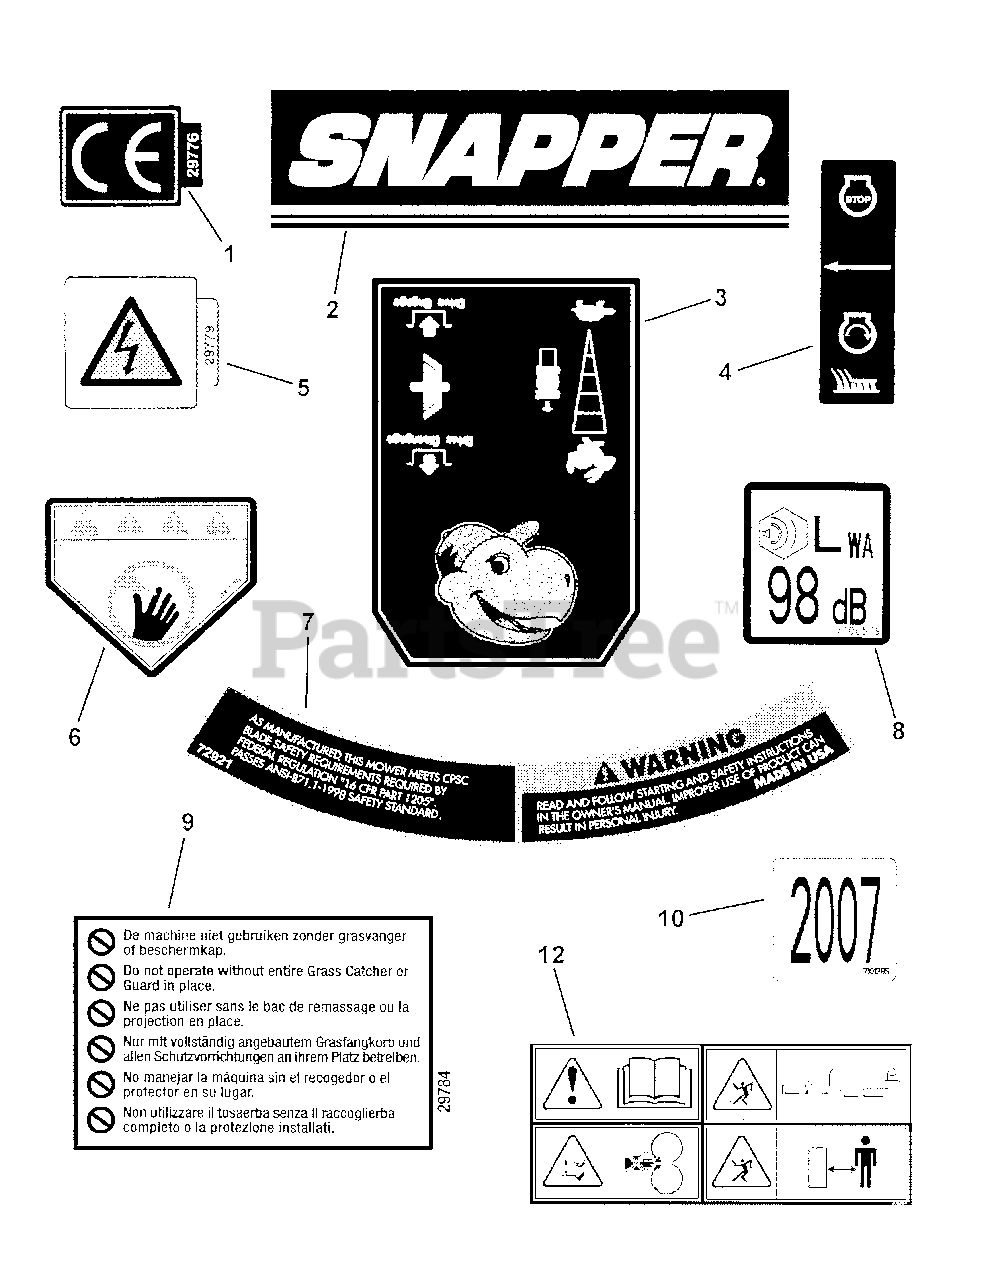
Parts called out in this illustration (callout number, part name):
1	DECAL,Euro Community (CE)
2	DECAL, SNAPPER Logo
3	DECAL, Control Head, Variable Speed
4	DECAL, OPC Bail International Symbol
5	DECAL, Spart Plug International Symbol
6	DECAL, Warning (Euro)
7	DECAL, Warning (Deck)
8	DECAL, Noise, 98 DB
9	DECAL, Deck/Chute International Warning
10	DECAL, 2007 Year of Manufacture
12	DECAL, Warning, Euro, Multi-Panel
